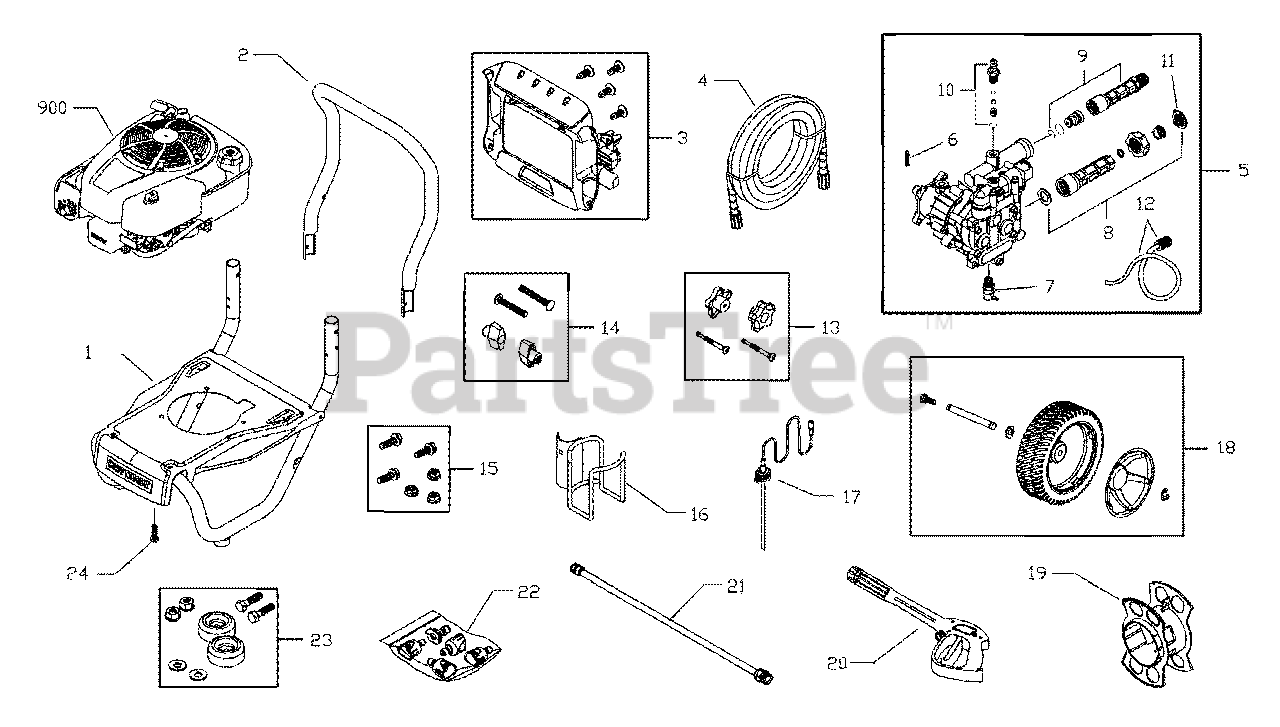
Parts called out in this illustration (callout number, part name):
1	BASE, w/Vib Mounts
3	KIT, Billboard w/Clips & Decals
4	HOSE
7	Valve, Thermal Relief
8	Kit, Water Inlet
9	Kit, Water Outlet
10	Kit, Chemical Injection
12	Kit, Chemical Hose
15	KIT, Pump Mounting Hardware
20	GUN
21	EXTENSION, QC
23	KIT, Vibration Mount
24	HHS, Trilobular, 3/8 - 16 x 1-1/4
